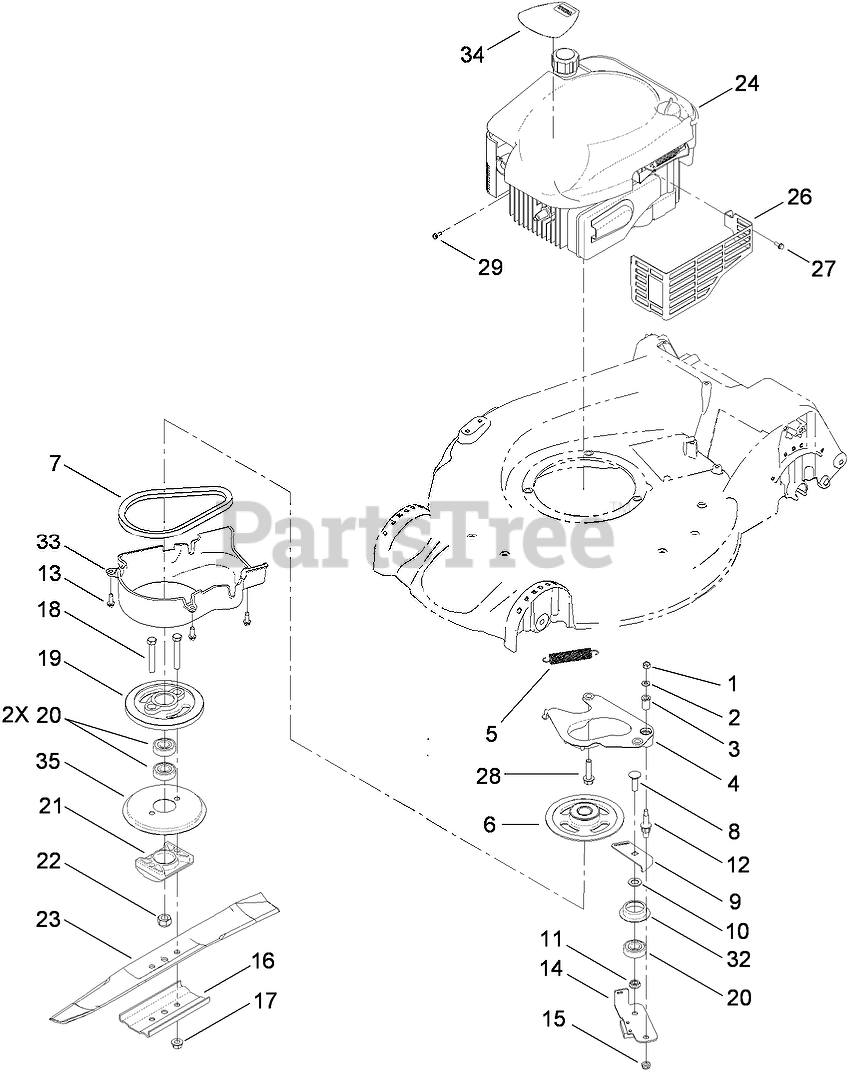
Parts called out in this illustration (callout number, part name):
1	NUT-LOCK, NI
2	WASHER-FLAT
3	BUSHING
4	PLATE-ANCHOR
5	SPRING-TENSION, BRAKE
6	PULLEY
7	BELT
8	BOLT-CARR
9	PLATE-GUIDE
10	WASHER-PLAIN
11	SPACER-BEARING
12	BOLT-SHOULDER
13	SCREW-HWHTF
14	BRAKE ARM ASM
16	SUPPORT-BLADE
17	NUT-LOCK
18	SCREW-HH
19	DRUM
20	BEARING-BALL
21	SUPPORT-BLADE
22	NUT-HEX
23	BLADE-RECYCLING
26	SHIELD-MUFFLER
27	SCREW-TAPTITE
28	SCREW-HWH
29	SCREW-HWH
32	RETAINER-BELT
34	DECAL-SHROUD
35	DISC
